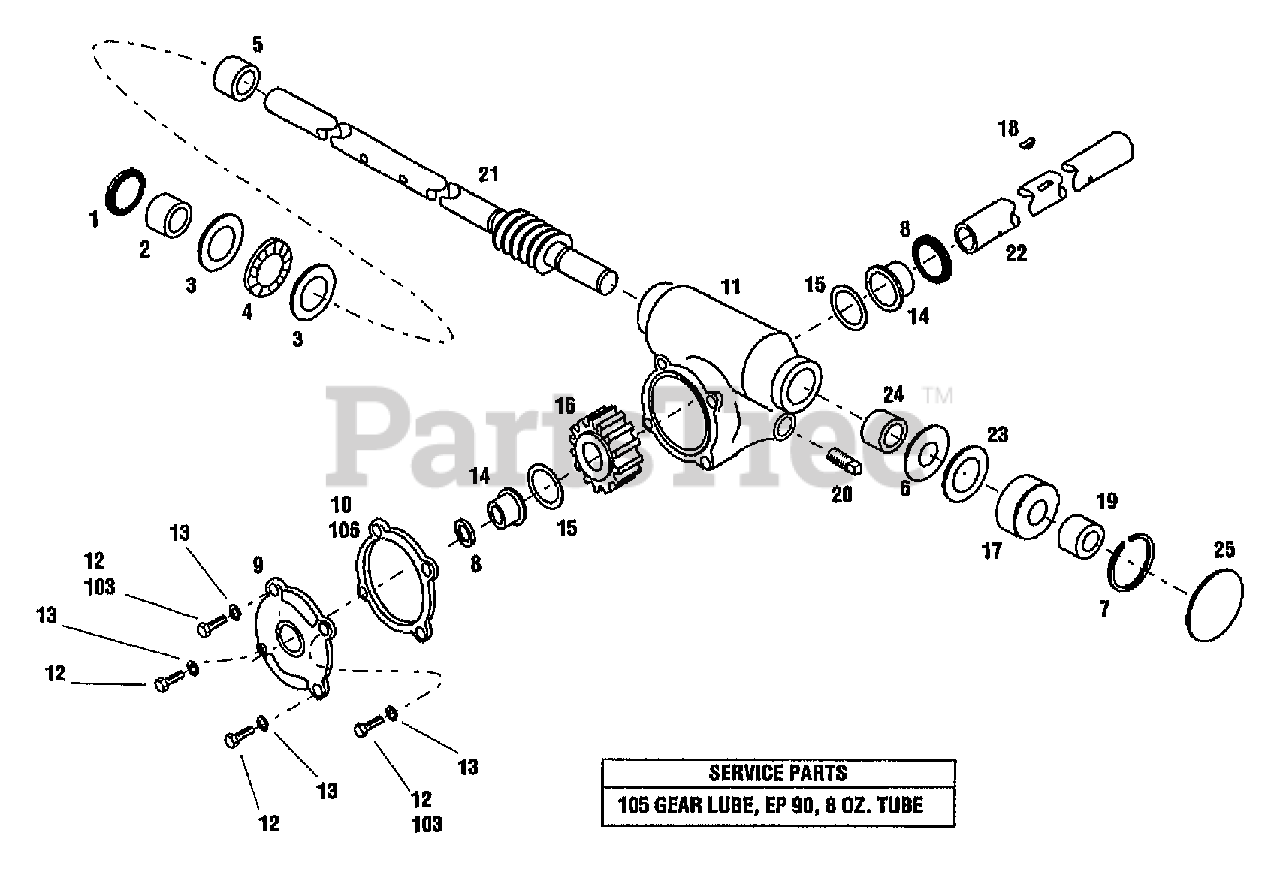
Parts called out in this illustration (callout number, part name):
1	SEAL-OIL 3/4 DIAMETER
2	BEARING-NEEDLE
3	RACE-THRUST
4	BEARING-THRUST
5	SPACER-1.0X.752X.302
6	WASHER
7	RING-RETAINING INTERNAL
8	SEAL-OIL
9	COVER-FLANGED
10	GASKET-COVER
11	CASE ONLY-GEAR
12	SCR-HH 1/4-20X.625 G5 ZP
13	WASHER-LK .25 ZP
14	BUSHING-FLANGE
15	RACE-THRUST
16	GEAR-WORM 20 TEETH
17	SPACER-1.503X.749X.56
18	KEY-WOODRUFF .25X.875
19	BEARING-NEEDLE
20	PLUG-SQ HEAD 1/4-18 NPT
21	ASSM-SHAFT IMPELLER 21"
22	SHAFT-AUGER
23	RACE-THRUST
24	SPACER-.812X.566X.448
25	PLUG-EXPANSION
103	LOCTITE-242 (.5 ML TUBE)
105	LUBE-EP90 8OZ
106	GASKET COMPOUND
